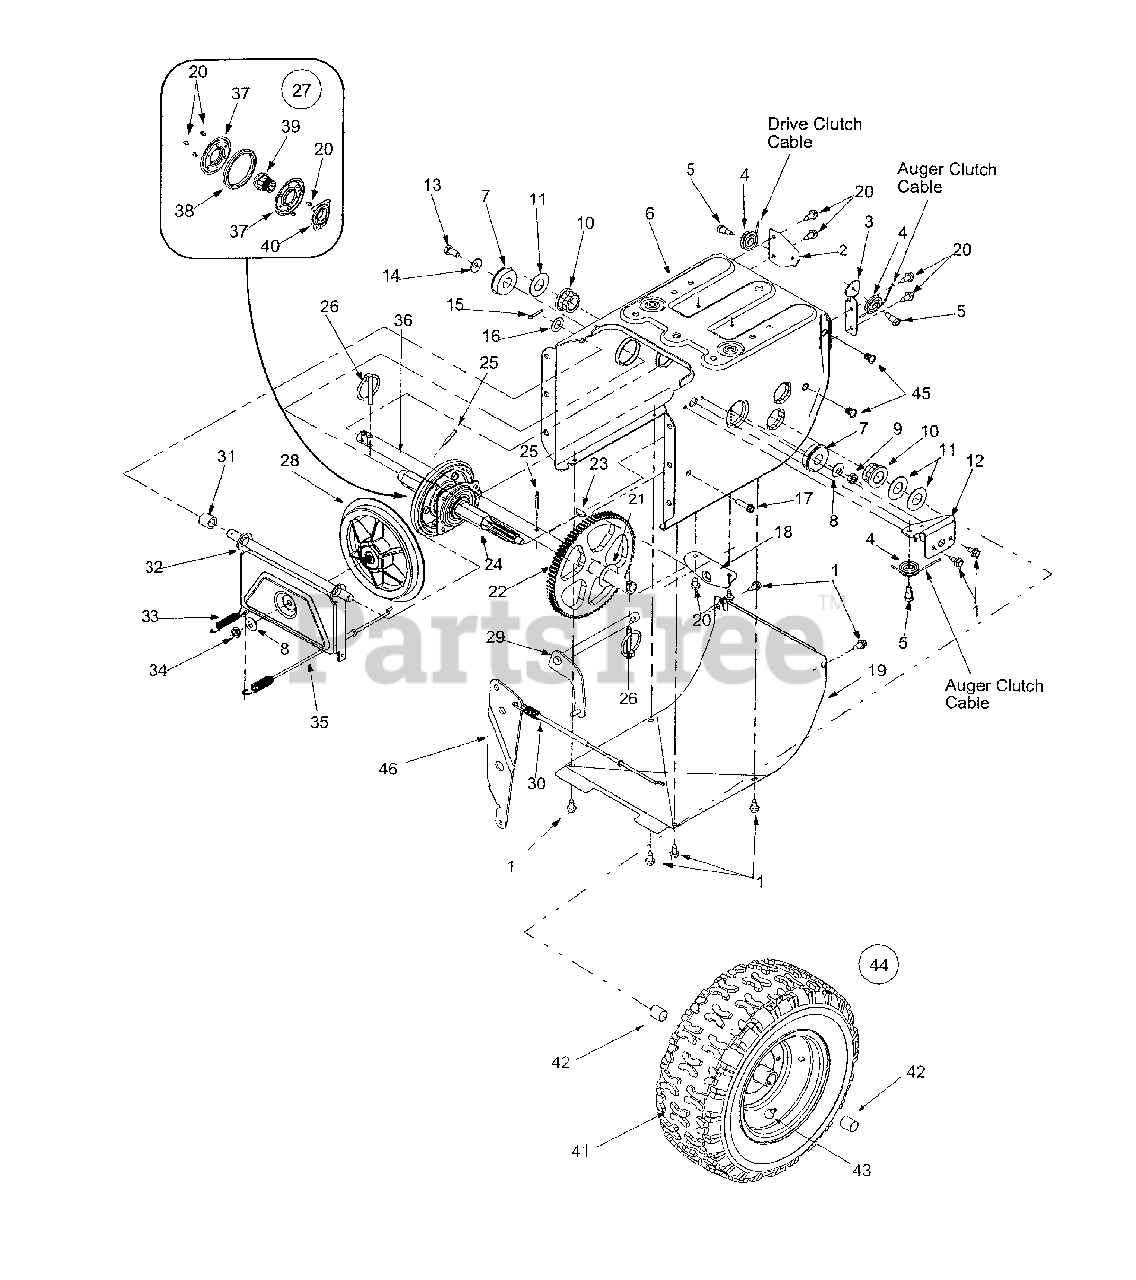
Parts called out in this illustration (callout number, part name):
1	Hex Screw
5	Hex Screw 1/4-28
8	Bell Washer
9	Lock Jam Nut
10	Hex Flange Bearing
11	Flat Washer
14	Bell Washer .340 ID x .872 OD
15	Cotter Pin
16	Flat Washer .536 ID x .930 OD
17	Hex Washer Screw 1/4-20
21	Flat Washer .760 ID x .50 OD
24	7-Tooth Shaft
25	Roll Pin
26	Clik Pin
27	Friction Wheel Assembly
28	Friction Wheel Disc
29	Wheel Shift Rod Assembly
30	Drive Cable
34	Jam Nut, 3/8-24
35	Drive Cable
37	Friction Wheel Side Plate
38	Friction Wheel Rubber
39	Friction Wheel Hub
40	Friction Wheel Bearing
42	Sleeve Bearing
43	Air Valve
